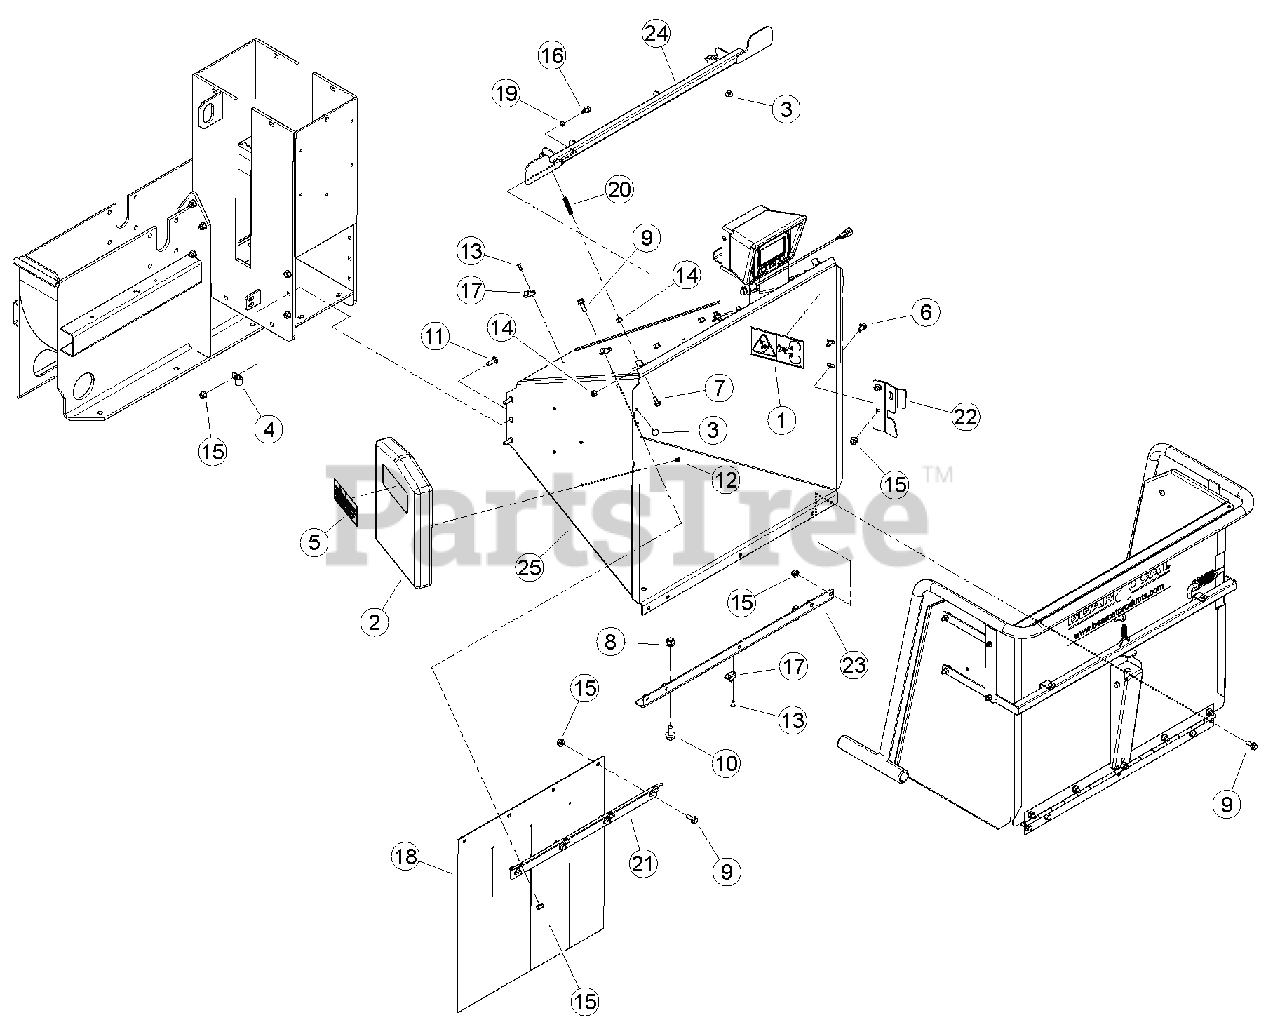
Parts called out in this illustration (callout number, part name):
1	DECAL, BLADE DANGER ISO
2	CONTAINER, INSTR. MANUAL
3	BUMPER, RUBBER
4	CLAMP, 9/16 COATED
5	DECAL, MUTILINGUAL MANUAL
6	BOLT, 3/8 X 1" GR5 CRG NC ZP
7	BOLT, 5/16 X 3/4 FLANGE NC
8	NUT, 1/2-13 NYLOCK FLANGE
9	BOLT, 3/8 X 1 FLANGE NC
10	BOLT, 1/2-13 1.00 GR5 FLANGE NC
11	BOLT, 3/8 X 1-1/4"GR5 CRG NC ZP
12	RIVET, AL BLIND 1/4 X 1/2 DOME HEAD
13	RIVET, AL BLIND 1/4 X 3/4 DOME HEAD
14	NUT, 5/16-18 NYLOCK-FLANGE
15	NUT, 3/8-16 NYLOCK FLANGE
16	BOLT, 5/16-18 X 3/4 ZP FLANGE SHOULDER
17	CLAMP, CABLE MOUNT
18	FLAP, 9 INCH CHUTE
19	BEARING, .375 X .50 X .25 LONG
20	SPRING, COMPRESSION .437 DIA X 2.0 LONG
21	SUPPORT, 9 INCH CHIPPER FLAP
22	PLATE, TRAY LATCH
23	ANGLE, INFEED SUPPORT
24	WELDMENT, 8/9" TOP SAFETY BAR
25	WELDMENT, BIG CHIPPER CHUTE
